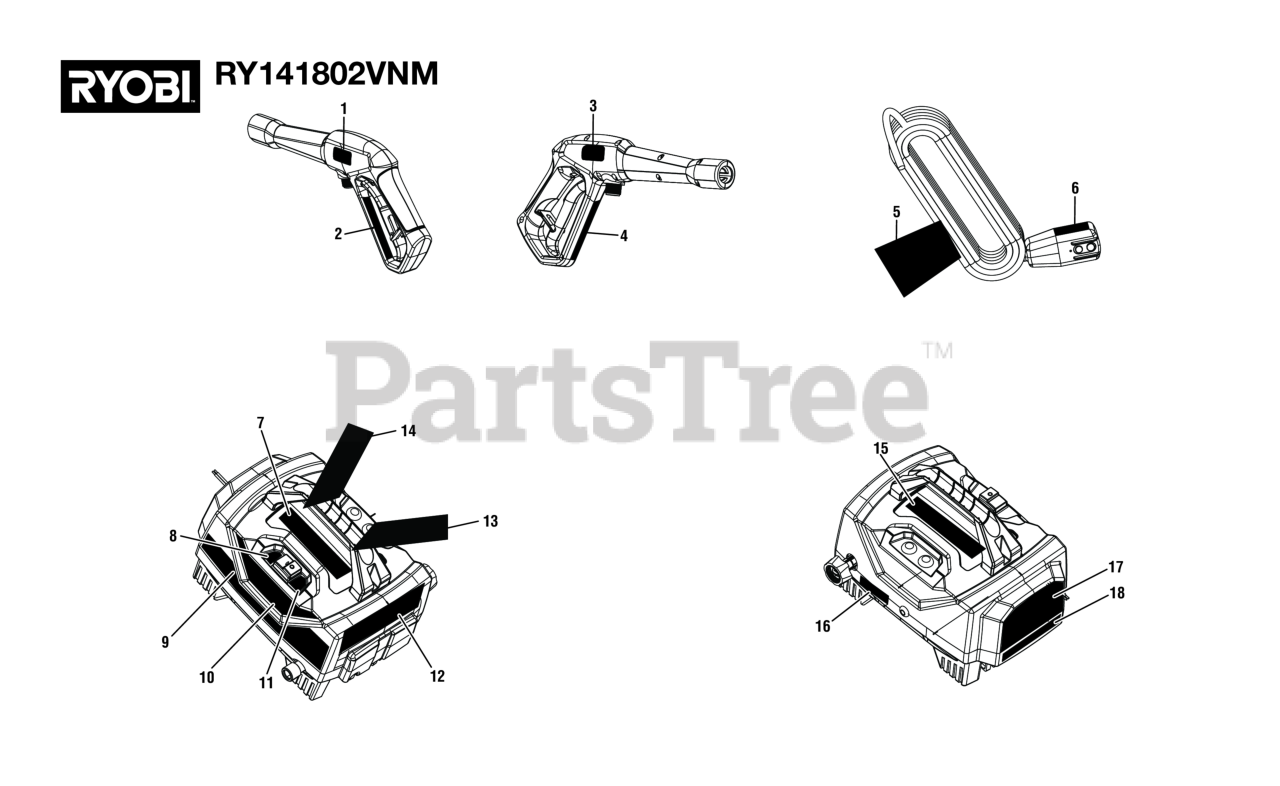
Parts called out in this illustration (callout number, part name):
1	Trigger Handle Warning Label (English)
2	Trigger Handle Warning Label (French/Spanish)
3	Trigger Handle Label (Logo Label)
4	Trigger Handle Data Label
5	Warning Label (Cord Wrap)
6	Power Cord Label
7	Quick Start Label
8	Off Label
9	Performance Label
10	Logo Label
12	Performance Label
13	Danger Hangtag (Spanish)
14	Nozzle Hangtag (PS141913)
15	Nozzle Selection Label
16	Inquires Label (Ryobi)
17	Regulatory Danger Label
18	Data Label
